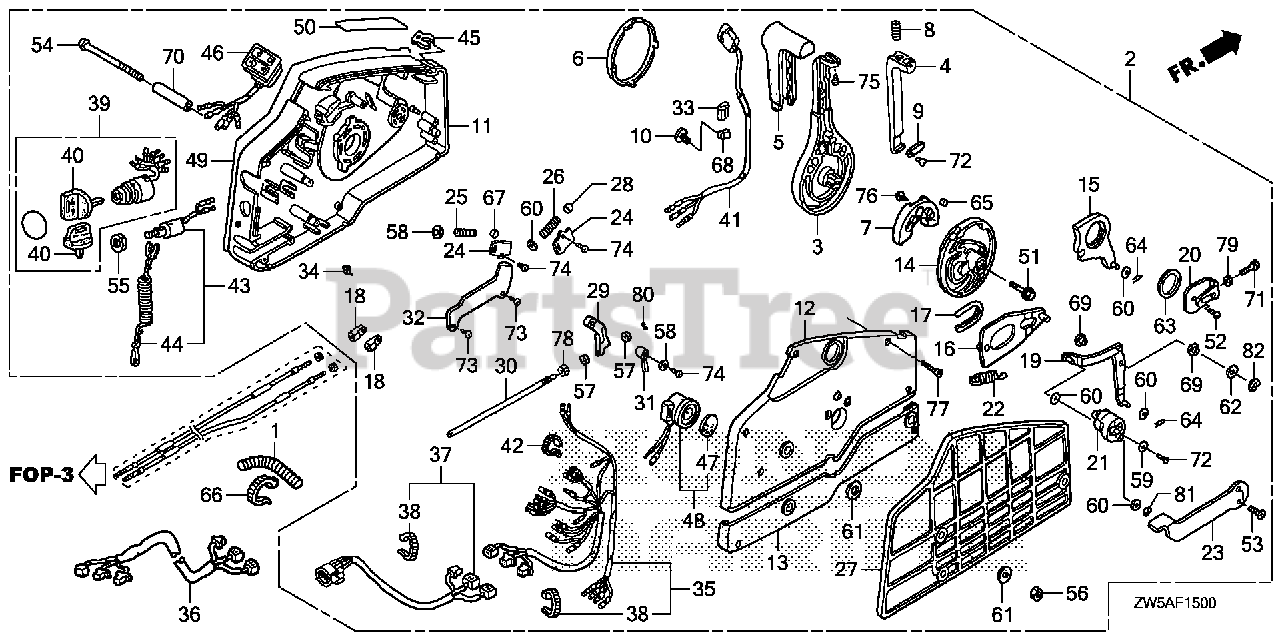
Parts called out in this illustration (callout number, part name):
1	TUBE, CORRUGATE (28MM)
2	BOX ASSY., REMOTE CONTROL (NHK MEC)
2	BOX ASSY., REMOTE CONTROL (P/T)
2	BOX ASSY., REMOTE CONTROL (P/T)(HI-LEX)
3	HANDLE, REMOTE CONTROL
4	LEVER, HANDLE LOCK
5	GRIP, REMOTE CONTROL HANDLE
6	CAP, HANDLE
7	BLOCK, NEUTRAL LOCK
8	SPRING, REMOTE CONTROL HANDLE
9	PLATE, LEVER SETTING
10	CLAMP, HARNESS
11	HOUSING, REMOTE CONTROL BOX (A)
12	HOUSING, REMOTE CONTROL BOX (B)
13	HOUSING, REMOTE CONTROL BOX (C)
14	WHEEL, CONTROL
15	ARM, SHIFT LINK
16	PLATE, SLIDING
17	COLLAR, SLIDING PLATE
18	PIVOT, SHIFT
19	ARM, LINK JOINT
20	BRACKET, LINK JOINT
21	WHEEL, ACCELERATOR
22	SPRING, ACCELERATOR WHEEL
23	LEVER, IDLE
24	PLATE, SPRING SETTING
25	SPRING, SHIFT CLICK
26	SPRING, CHOKE RETURN
27	SPACER, REMOTE CONTROL BOX
28	SPACER, CLICK SPRING
29	BLOCK, THROTTLE FRICTION
30	BOLT, FRICTION
31	SPACER, NEUTRAL SWITCH
32	CLAMP, POWER TILT CORD
33	PIPE, HARNESS GUIDE
34	SPACER, CABLE CLAMP
35	CABLE ASSY., REMOTE CONTROL (B)
36	CABLE ASSY., REMOTE CONTROL EXTENSION
37	CABLE ASSY., SWITCH PANEL
38	TIE, CABLE (2.4X92) (NATURAL)
39	SWITCH ASSY., COMBINATION
40	KEY ASSY., COMBINATION SWITCH (35100-ZV5-003 ONLY)
41	SWITCH ASSY., POWER TRIM-TILT
42	BAND (BLACK 3.5X140)
43	SWITCH ASSY., EMERGENCY STOP
44	WIRE, EMERGENCY
45	CLIP, EMERGENCY LOCK
46	LAMP ASSY., INDICATION (2-LED)
47	PLATE, TURN SIGNAL BUZZER
48	BUZZER, WARNING
49	PLATE, REMOTE CONTROL (CAUTION PICT=SILVER)
49	PLATE, REMOTE CONTROL (COUTION COLOR=RED & YELLOW)
50	MARK, FAST IDLE
51	BOLT, FLANGE (8X35)
52	SCREW, PAN (6X10)
53	SCREW, FLAT (5X12)
54	SCREW (6X95)
55	NUT, HEX. (16MM)
56	NUT, HEX. (6MM)
57	WASHER, PLAIN (4MM)
58	WASHER, PLAIN (5MM)
59	WASHER, PLAIN (5MM)
60	WASHER, PLAIN (6MM)
61	WASHER (6MM)
62	WASHER, PLAIN (8MM)
63	WASHER (28MM)
64	PIN, LOCK (6MM)
65	PIN (6X6)
66	BAND, SELF-LOCK
67	ROLLER, CLICK
68	CLIP, WIRE HARNESS (6.3MM)
69	COLLAR, LINK JOINT
70	COLLAR, DISTANCE (6X10X43.5)
71	BOLT, HEX. (5X16)
72	SCREW, PAN (5X10)
73	SCREW, TAPPING (5X8)
74	SCREW, TAPPING (5X10)
75	SCREW, TAPPING (5X12)
76	SCREW, TAPPING (6X16)
77	SCREW, TAPPING (5X25)
78	NUT, HEX. (6MM)
79	NUT, HEX. (5MM)
80	E-RING (3MM)
81	E-RING (4MM)
82	E-RING (7MM)
